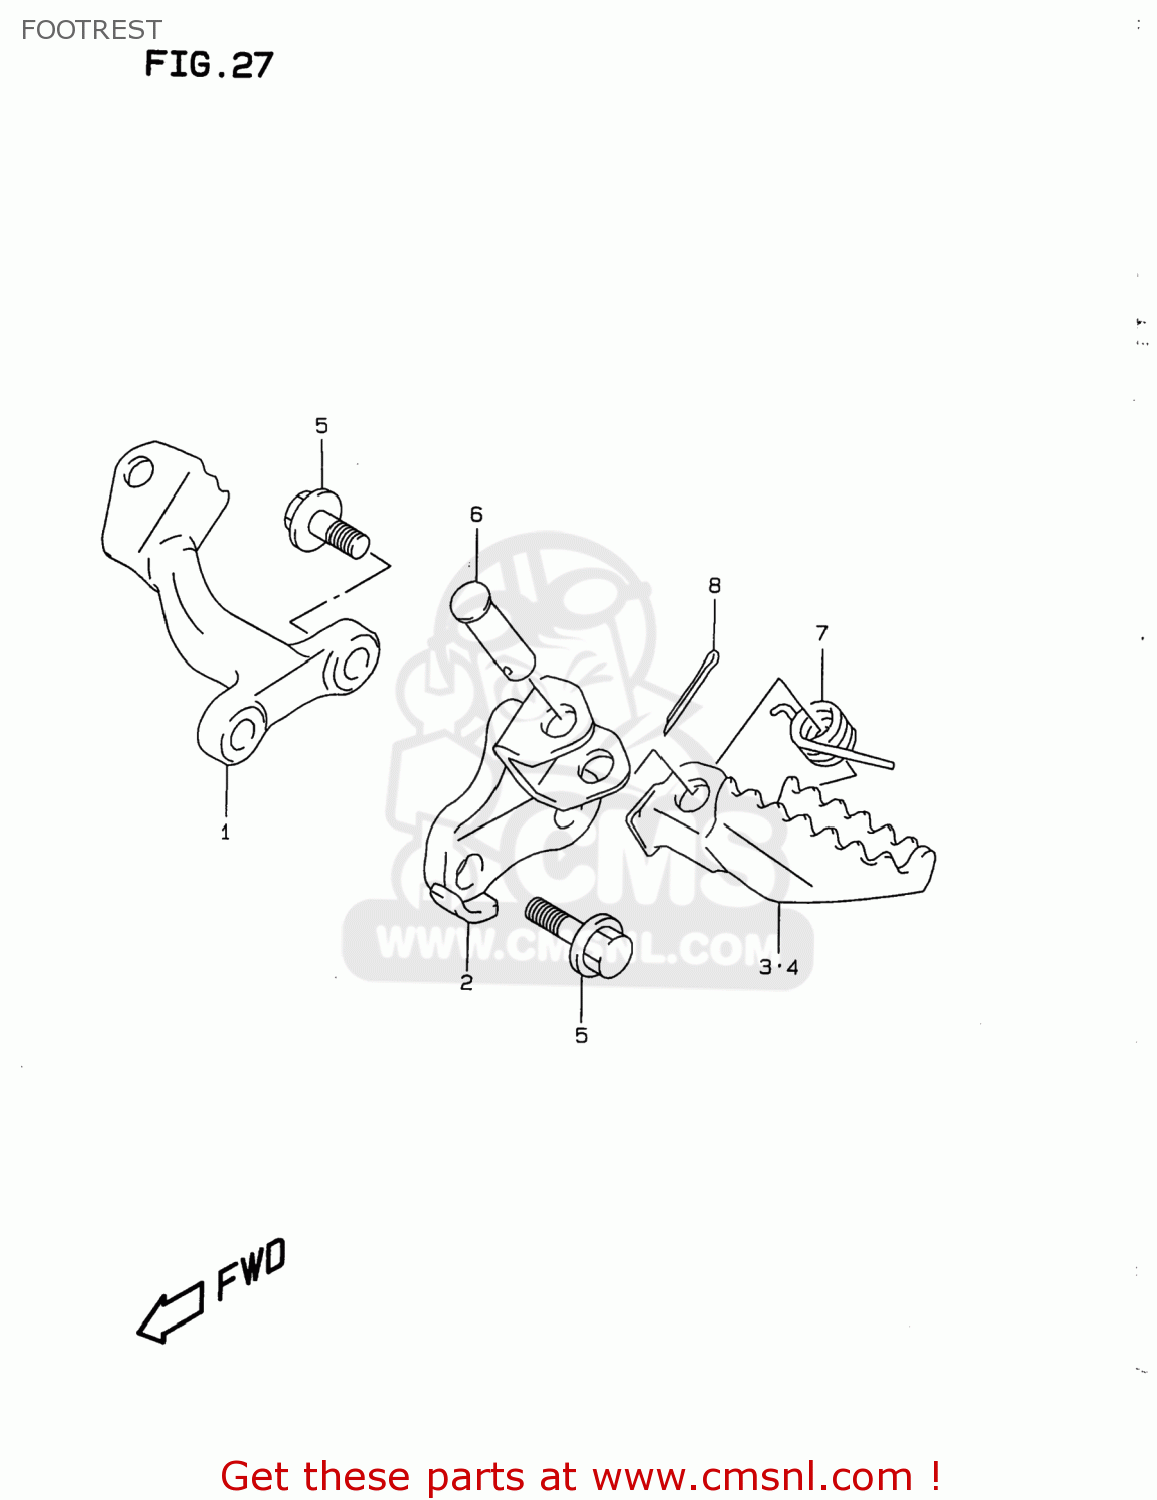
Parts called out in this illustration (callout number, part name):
1	BRACKET,FRONT FOOTREST
2	BRACKET,FR FOOTREST,L
3	FOOTREST,RIGHT
4	FOOTREST,LEFT
5	BOLT(10X40)
6	PIN
7	SPRING
8	PIN
